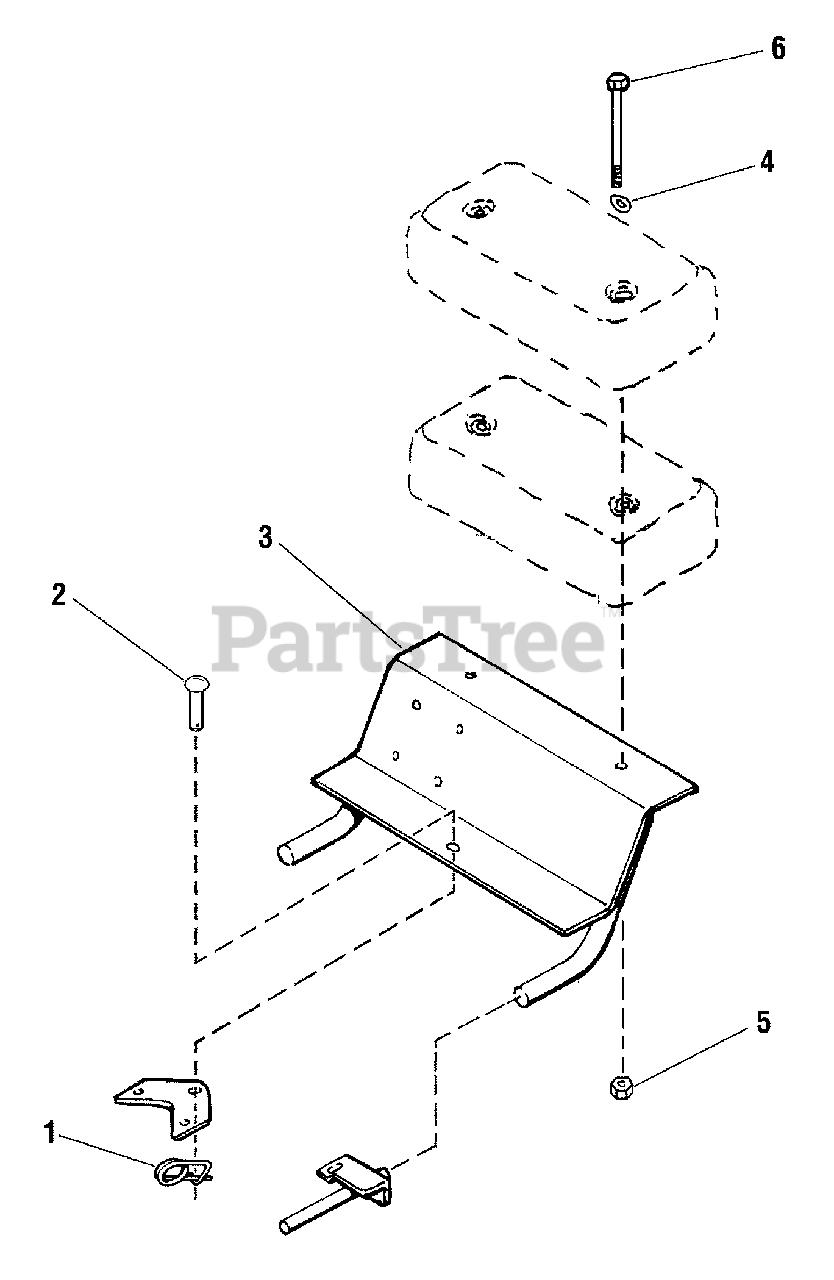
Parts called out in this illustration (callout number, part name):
1	CLIP PIN, Safety
2	PIN, Clevis
5	NUT, Lock, 7/16-14
6	CAPSCREW, 7/16-14-8 (For Use With Two Weights)
